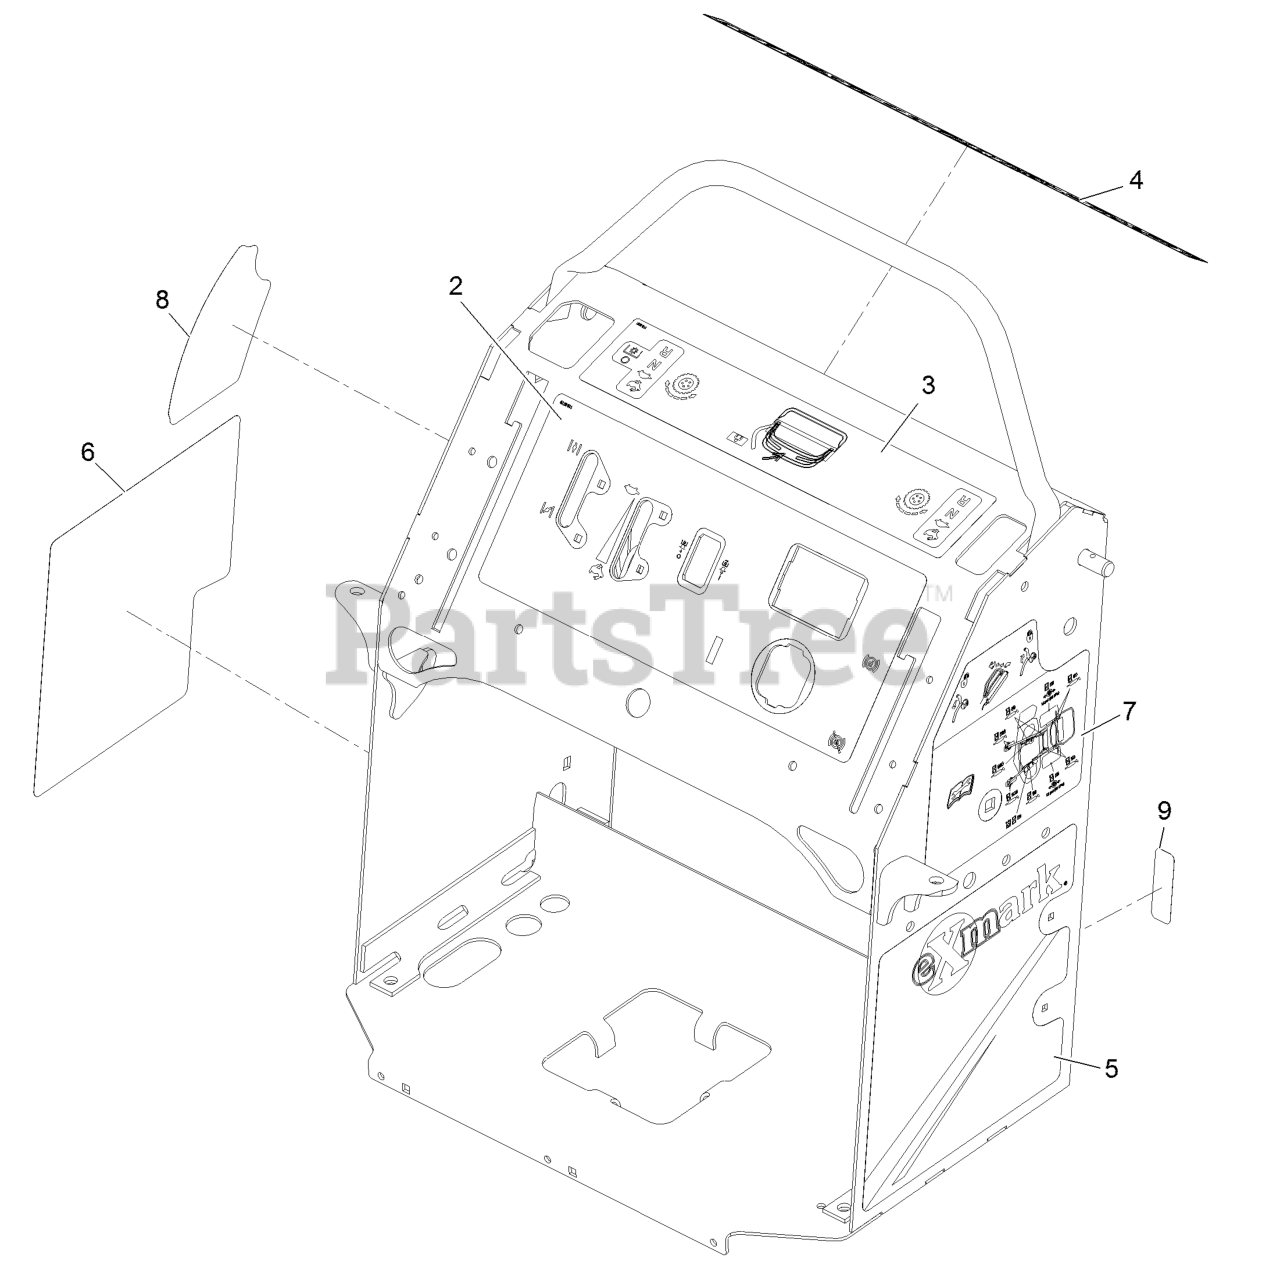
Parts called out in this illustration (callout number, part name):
2	DECAL-CONTROL PANEL
3	DECAL-MOTION CONTROL
4	DECAL-WARNING
5	DECAL-LH PANEL
6	DECAL-RH PANEL
7	DECAL-SERVICE AID
8	DECAL-HEIGHT OF CUT
9	DECAL-FUSE
